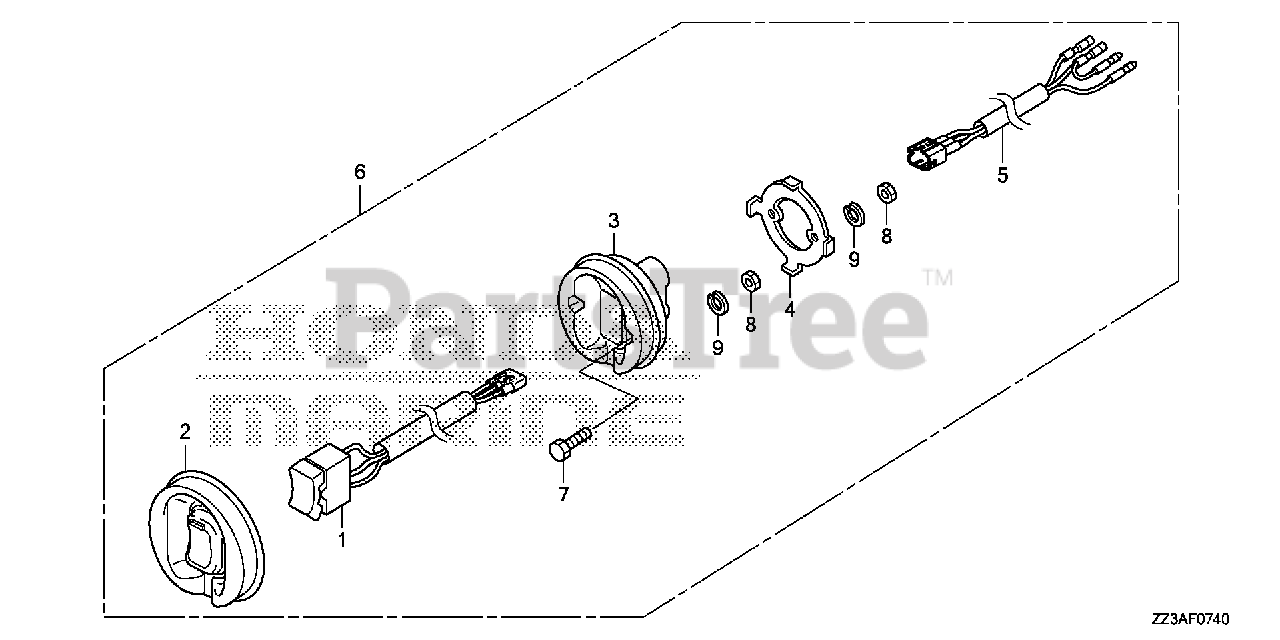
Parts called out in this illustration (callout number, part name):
1	SWITCH ASSY., TROLLING CONTROL
2	RUBBER, TROLLING CONTROL SWITCH PANEL
3	BODY, TROLLING CONTROL SWITCH PANEL
4	BRACKET, TROLLING CONTROL SWITCH PANEL
5	HARNESS, TROLLING CONTROL SWITCH PANEL
6	PANEL ASSY., TROLLING CONTROL
7	BOLT, HEX. (4X20)
8	NUT, HEX. (4MM) (NOT AVAILABLE)
9	WASHER, SPRING (4MM)
